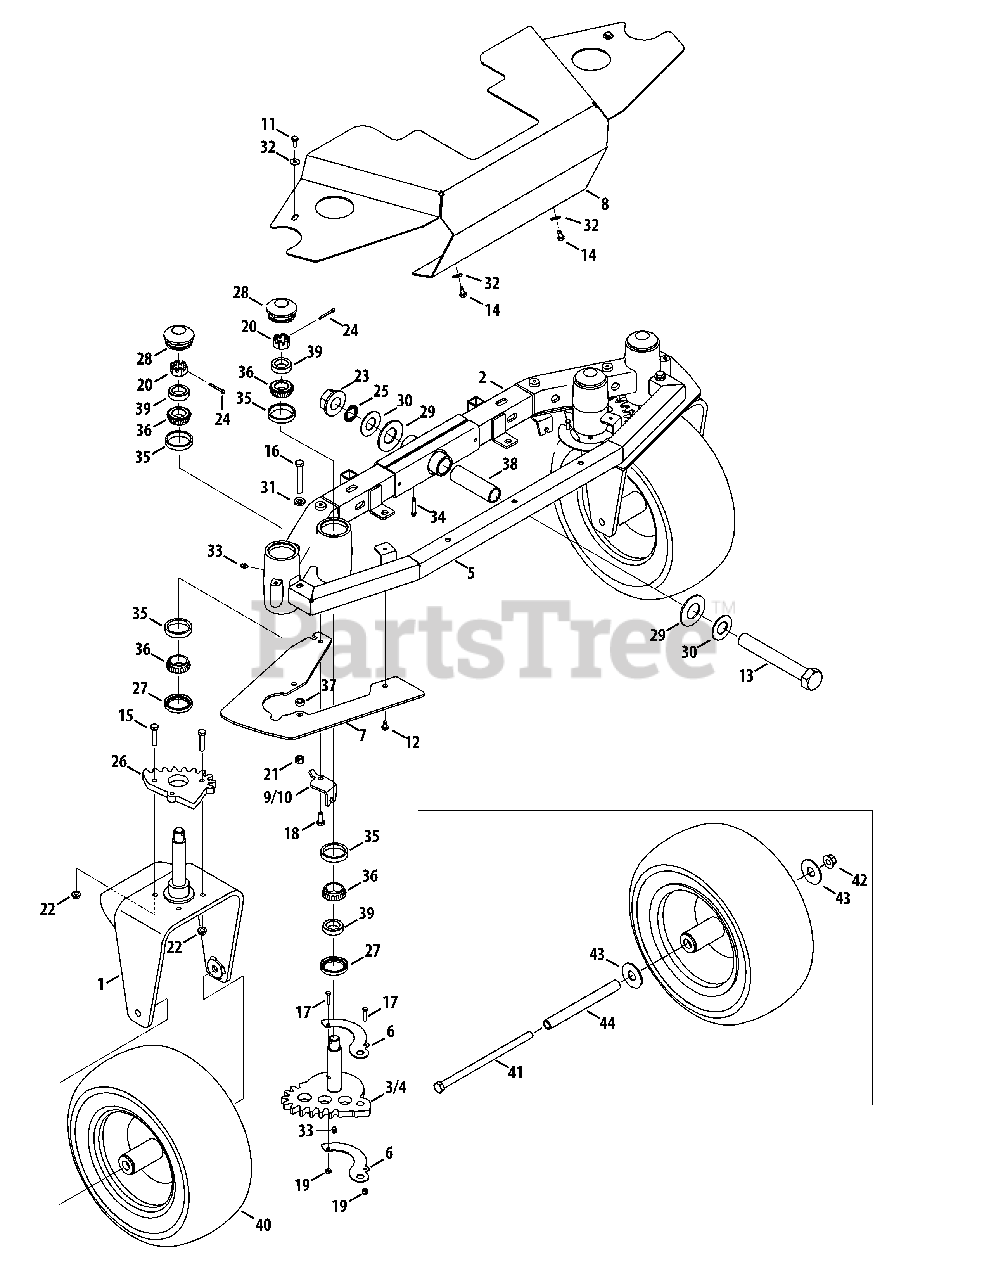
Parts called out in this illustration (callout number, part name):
1	Yoke Assembly
2	Axle Assembly
3	LH Steering Gear
4	RH Steering Gear
6	Gear Cable Mounting Bracket
7	Gear Panel Cover
9	RH Steering Cable Bracket
10	LH Steering Cable Bracket
11	Hex Cap Screw, 1/4-20 x .625
12	Screw, 1/4-20 x .5
13	Hex Cap Screw, 1-14 x 7.0
14	Hex Flange Screw, 1/4-20 x .500
15	Hex Cap Screw, 5/16-18 x 1.50
16	Hex Cap Screw, 3/8-16 x 2.50
17	Machine Screw, #10-24 x 1.00
18	Hex Cap Screw, 5/16-18 x .75
19	Nut, #10-24, Hexlock
20	Nut, 3/4-16, Slotted
21	Nut, 3/8-16, Hexlock
22	Nut, 5/16-18, Flangelock
23	Nut, 1.0-14, Flangelock
24	Cotter Pin, 5/32 x 1.25
25	Retainer Ring
26	Steering Gear
27	Seal, 14858
28	Axle Grease Cap
29	Bell Washer, 1.25 x 2.50 x .180
30	Washer, 1.00 x 2.00 x .075
31	Washer, .407 x .812 x .135
32	Washer, .260 x .720 x .060
33	Grease Fitting, 1/4-28
34	Grease Fitting, 1 39/64
35	Cup Bearing
36	Cone Bearing
37	Spacer, .380 x .625 x .265
38	Spacer, 1.005 x 1.247 x 4.1
39	Spacer, 1.00 x 1.50 x .437
40	Wheel Assembly, 15 x 6.5-8
41	Hex Cap Screw, 1/2-13 x 9.5
42	Nut, 1/2-13, Flangelock
43	Washer, .781 x 2.00 x .105
44	Spacer, .51 x .750 x 7.38
